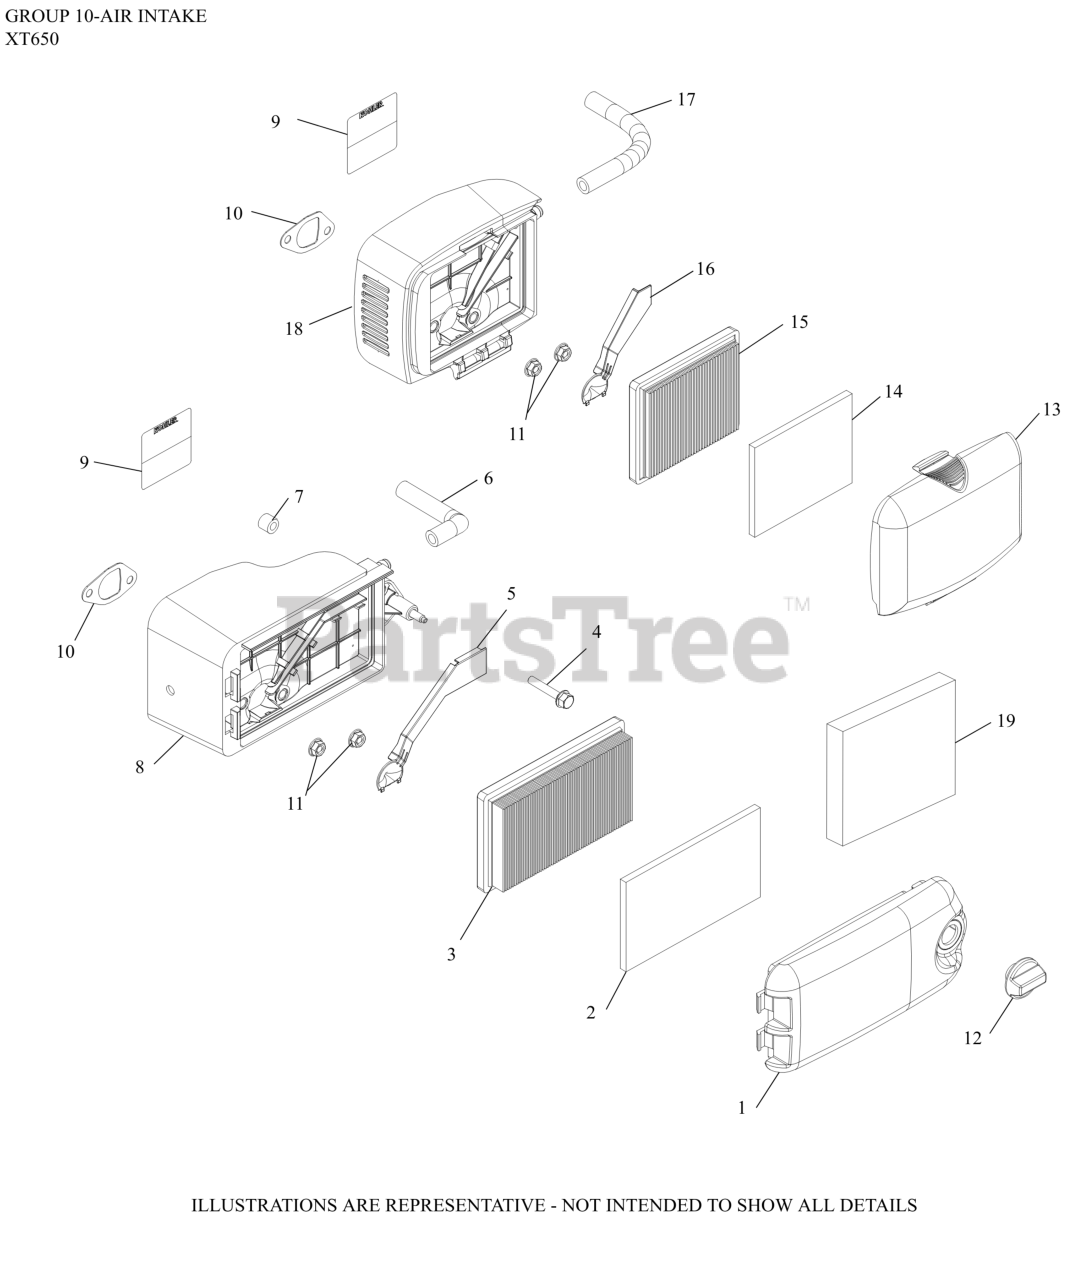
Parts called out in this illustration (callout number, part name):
1	COVER, AIR CLEANER
3	ELEMENT, AIR CLEANER-(#1408319S)
4	SCREW, HEX FLANGE (M6)
5	COVER, A/C BASE (BREATHER GAS)
6	HOSE, BREATHER
7	SPACER, AIR CLEANER BASE
8	KIT, AIR CLEANER BASE
9	NAMEPLATE, SERVICE
10	KIT, INTAKE GASKET
12	KNOB-USE 14 341 07-S
